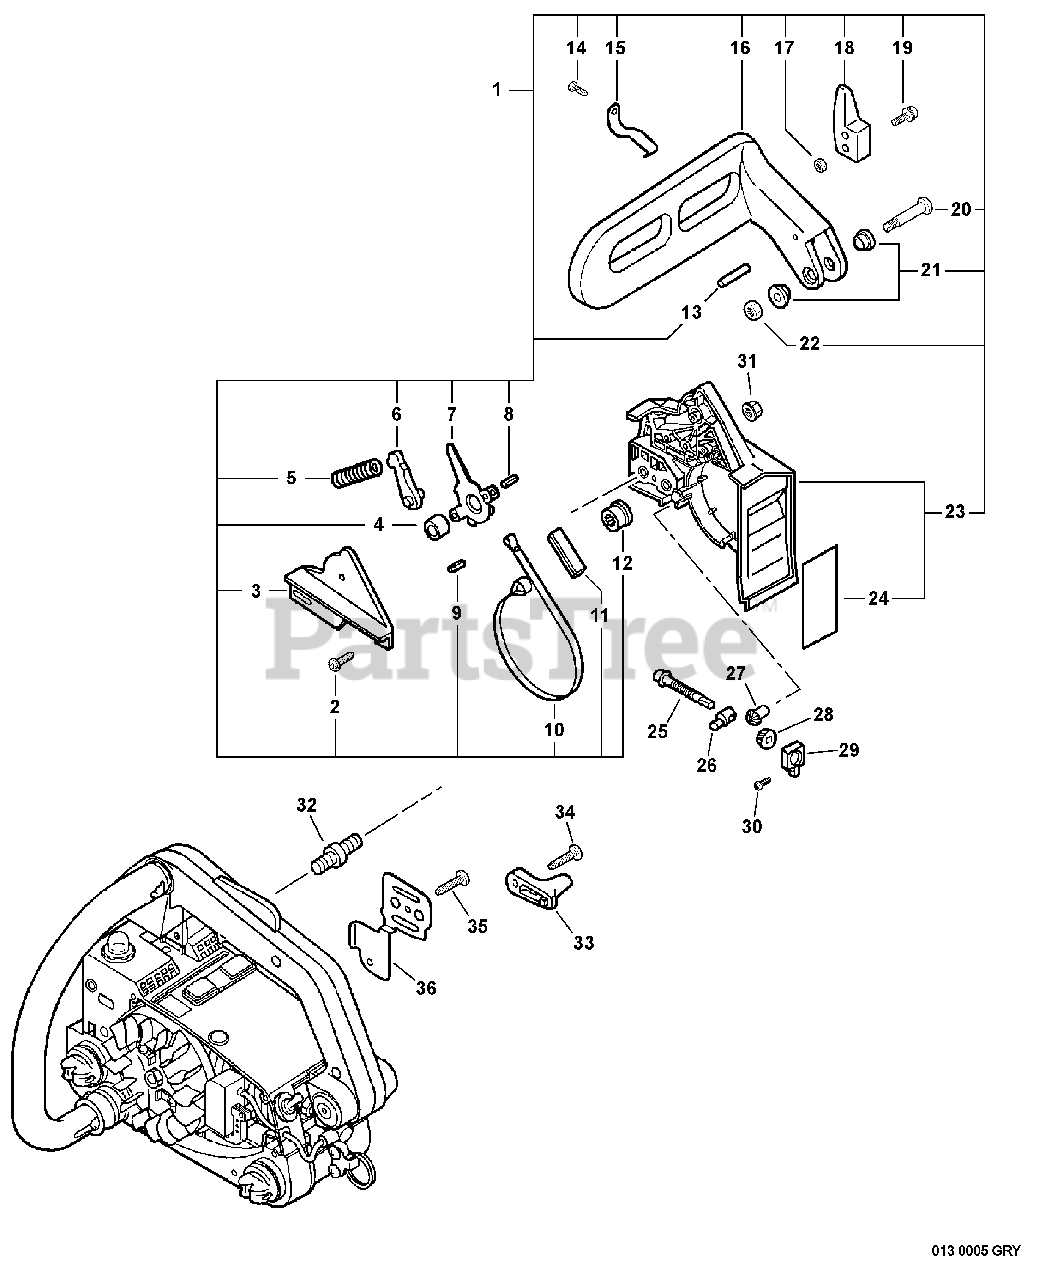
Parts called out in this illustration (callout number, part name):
1	CHAIN BRAKE ASSY
2	SCREW - 4X12 -- TAPPING
3	COVER, BRAKE - GRAY
4	SPACER - 8
5	SPRING, BRAKE
6	STOPPER, BRAKE
7	LEVER, BRAKE
8	PIN - SPRING -- 4X8
9	PIN - SPRING -- 2.5X12
10	BAND, BRAKE
12	ADJUSTER, BRAKE BAND
13	ROLLER - 4X23.8
14	SCREW - 4X12 -- TAPPING
15	SPRING, RETURN
16	LEVER, BRAKE - ORANGE
18	WEIGHT, BRAKE
19	SCREW - 4X22
20	SCREW - 5X32
22	LOCKNUT - 5
23	GUARD, SPROCKET - GRAY
24	DEFLECTOR, HEAT
25	SCREW, TENSIONER
26	TENSIONER, CHAIN
27	GEAR - PINION
28	GEAR - BEVEL
29	BRACKET, TENSIONER
30	SCREW - 4X12 -- TAPPING
31	NUT - 6 -- FLANGE
32	STUD, GUIDE BAR
33	CATCHER, CHAIN
34	SCREW - 5X20 -- TAPPING
35	SCREW - 4X10
36	PLATE, GUIDE - OUTER
